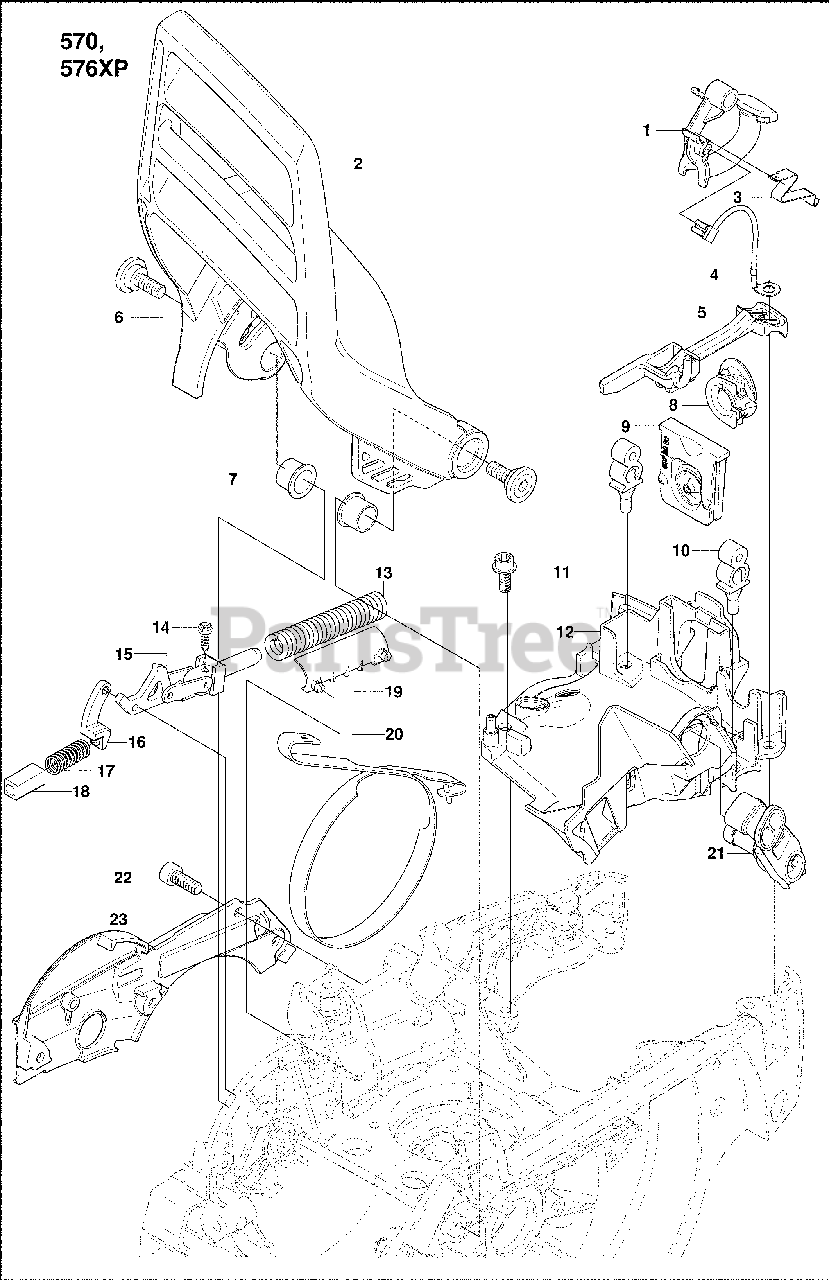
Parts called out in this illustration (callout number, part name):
2	Chain Brake
5	Choke Control Lever
13	Brake Spring
15	Knee Joint
17	Lock Spring
19	Support
20	Brake Band
